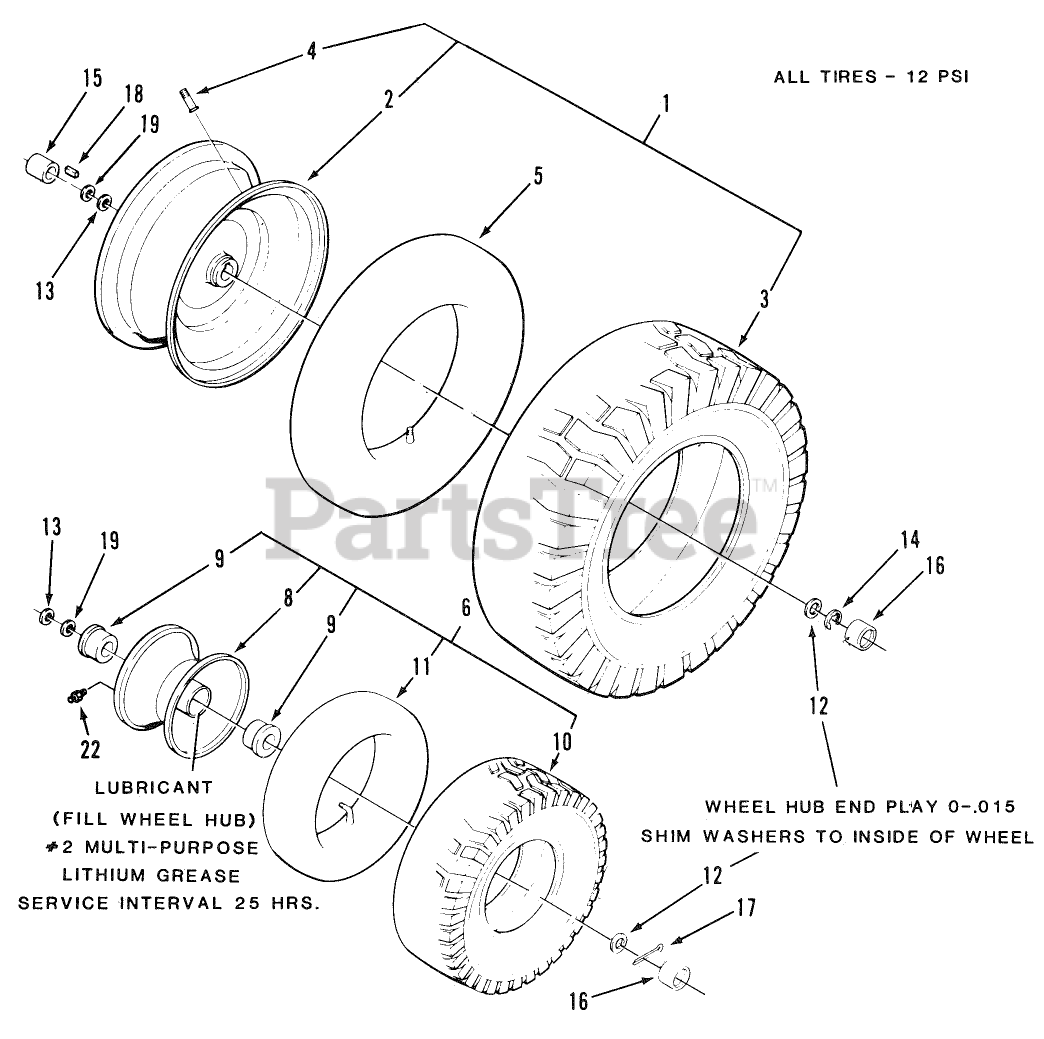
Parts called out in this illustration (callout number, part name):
4	VALVE
6	ASSY-WHEEL TIRE
8	ASS'Y-WHEEL
9	BUSHING-FLANGE
12	WASHER-FLAT
13	WASHER
15	LH AXLE SPACER
18	SQ KEY
19	WASHER-SHIM
